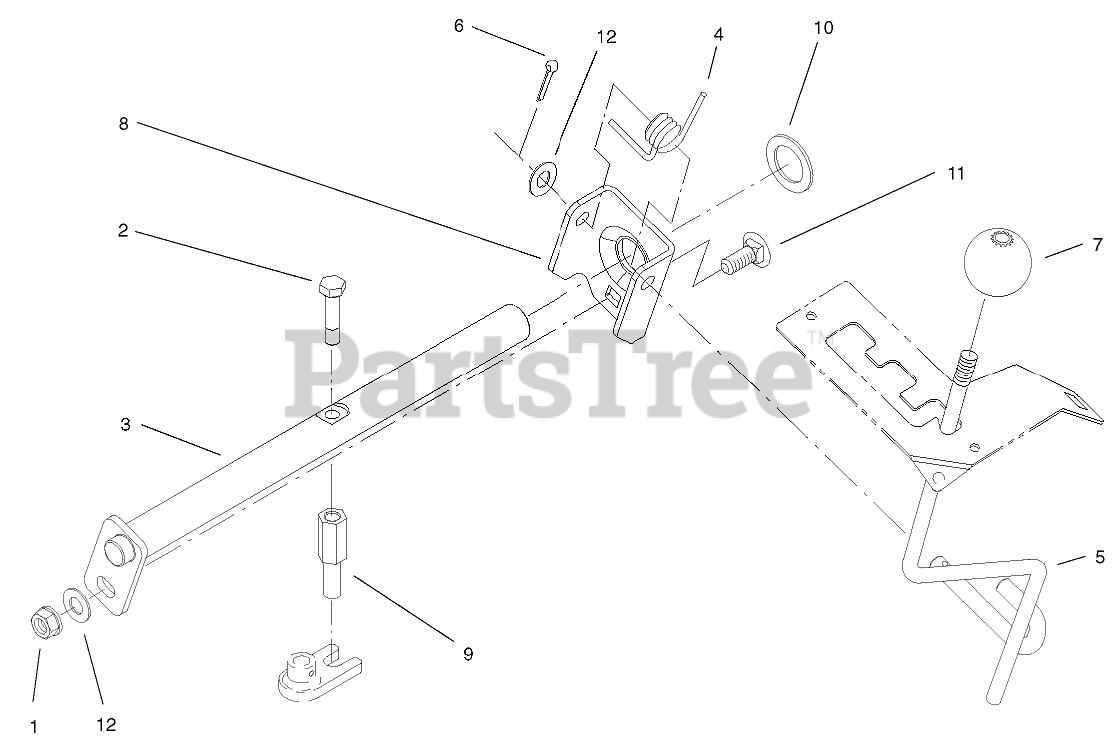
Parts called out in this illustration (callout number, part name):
1	NUT-LOCK, NI
2	SCREW-THREAD LOCKING
3	SHIFT ROD ASM
4	SPRING-TORSION
5	LEVER-SHIFT
6	PIN-COTTER
7	KNOB-HI / LO SHIFT
8	BRACKET-PIVOT
9	ROD-PIVOT, SHIFT
10	SPACER
11	SCREW-CARR
12	WASHER-FLAT
